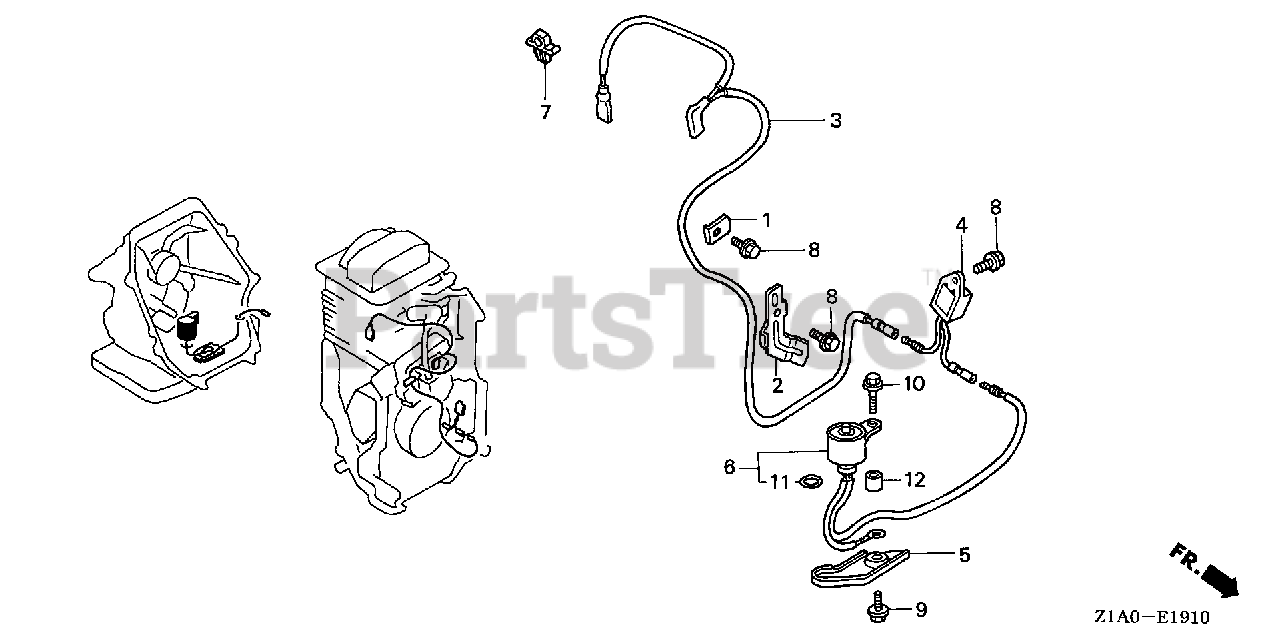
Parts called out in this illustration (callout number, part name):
1	CLAMP, STOP SWITCH WIRE
2	CLAMP, WIRE
3	WIRE, STOP SWITCH
4	ALERT UNIT, OIL
5	PROTECTOR, SWITCH
6	SWITCH, OIL LEVEL
7	HOLDER, STOP SWITCH WIRE Use up to Engine SN 2056819.
8	BOLT, FLANGE (6X12) (CT200)
9	BOLT, FLANGE (6X14)
10	BOLT, FLANGE (6X28) (CT200) Use up to Engine SN 1530314.
11	O-RING (11.8X2.4)
12	COLLAR (6.6X13.8X14.5)
